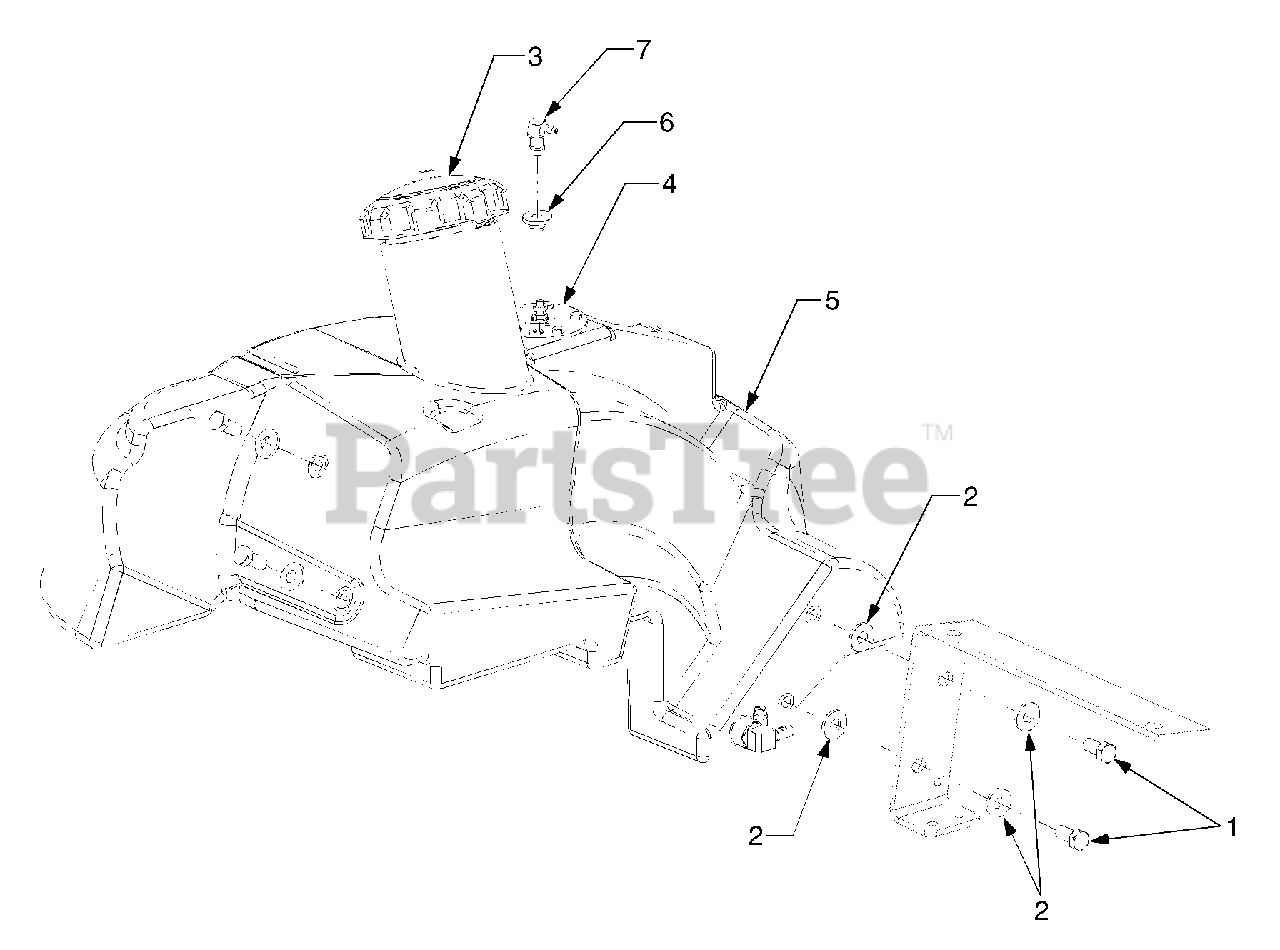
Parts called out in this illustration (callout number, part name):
1	Screw, Hex Cap, Lock 3/8-16 x .75 GR5
2	Washer, Flat, .385 x .87 x .092
3	Cap, Fuel
4	Sensor, Fuel Level
5	Tank, Fuel
6	Bushing, Rubber
7	Fitting, Fuel Return
